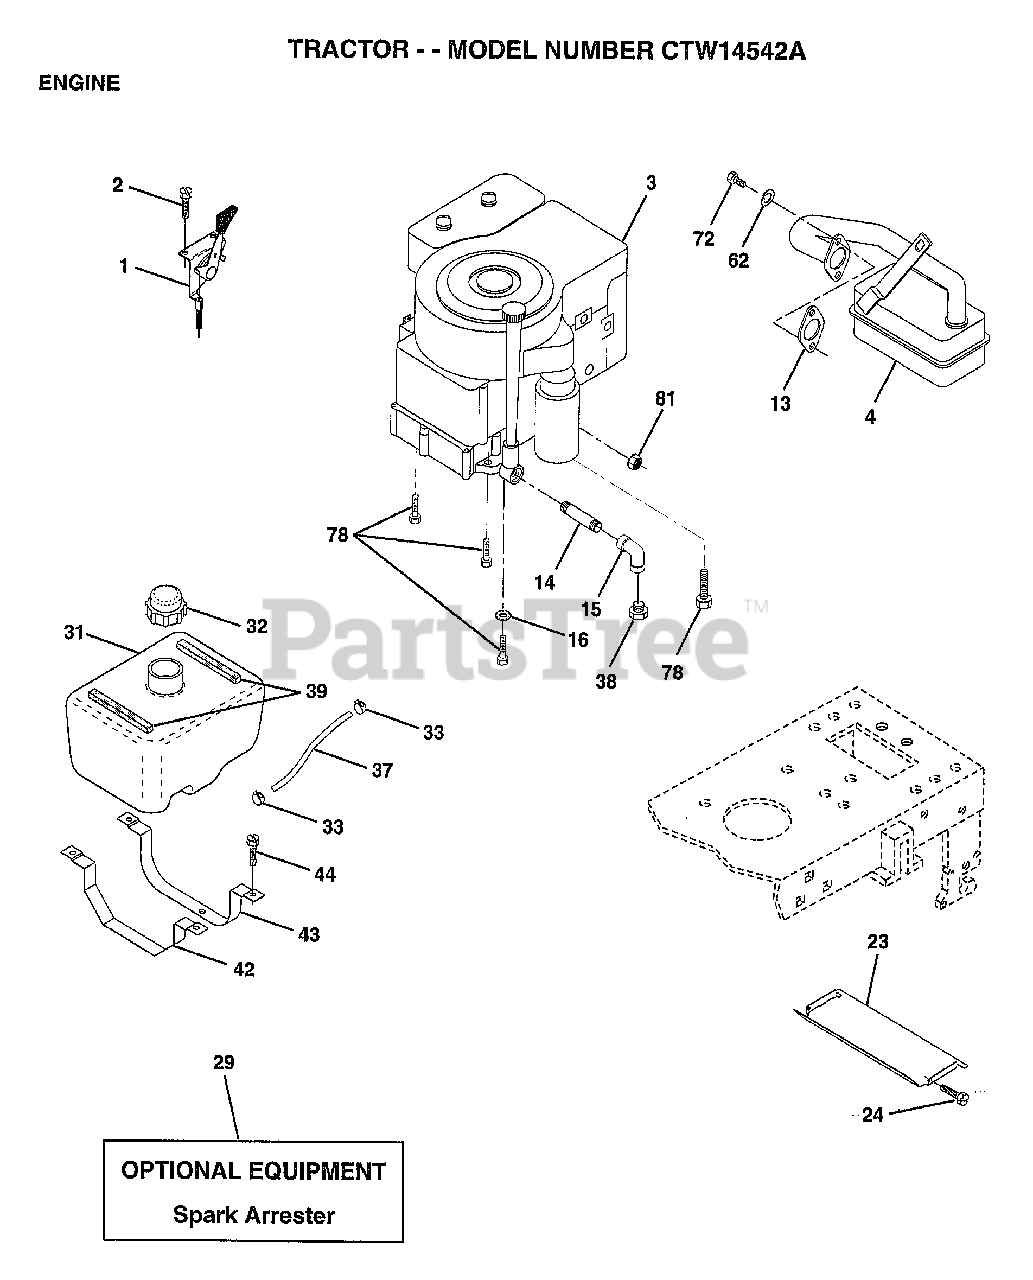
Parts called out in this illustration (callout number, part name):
1	THROTTLE CONTROL
2	SCREW LT
4	MUFFLER
13	GASKET ENG 1 313 LD TIN PLATED
14	PIPE NIPPLE
15	ELBOW
16	LOCKWASHER
23	HEAT SHIELD
24	SCREW
31	TANK FUEL 1.9 NAT
32	CAP ASM FUEL
33	HOSE CLAMP
37	FUEL LINE T
39	"STRIP,FORM"
42	STRAP TANK FUEL
43	STRAP TANK FRONT
44	SCREW
62	LOCKWASHER
72	SCREW
78	SCREW
81	NUT
